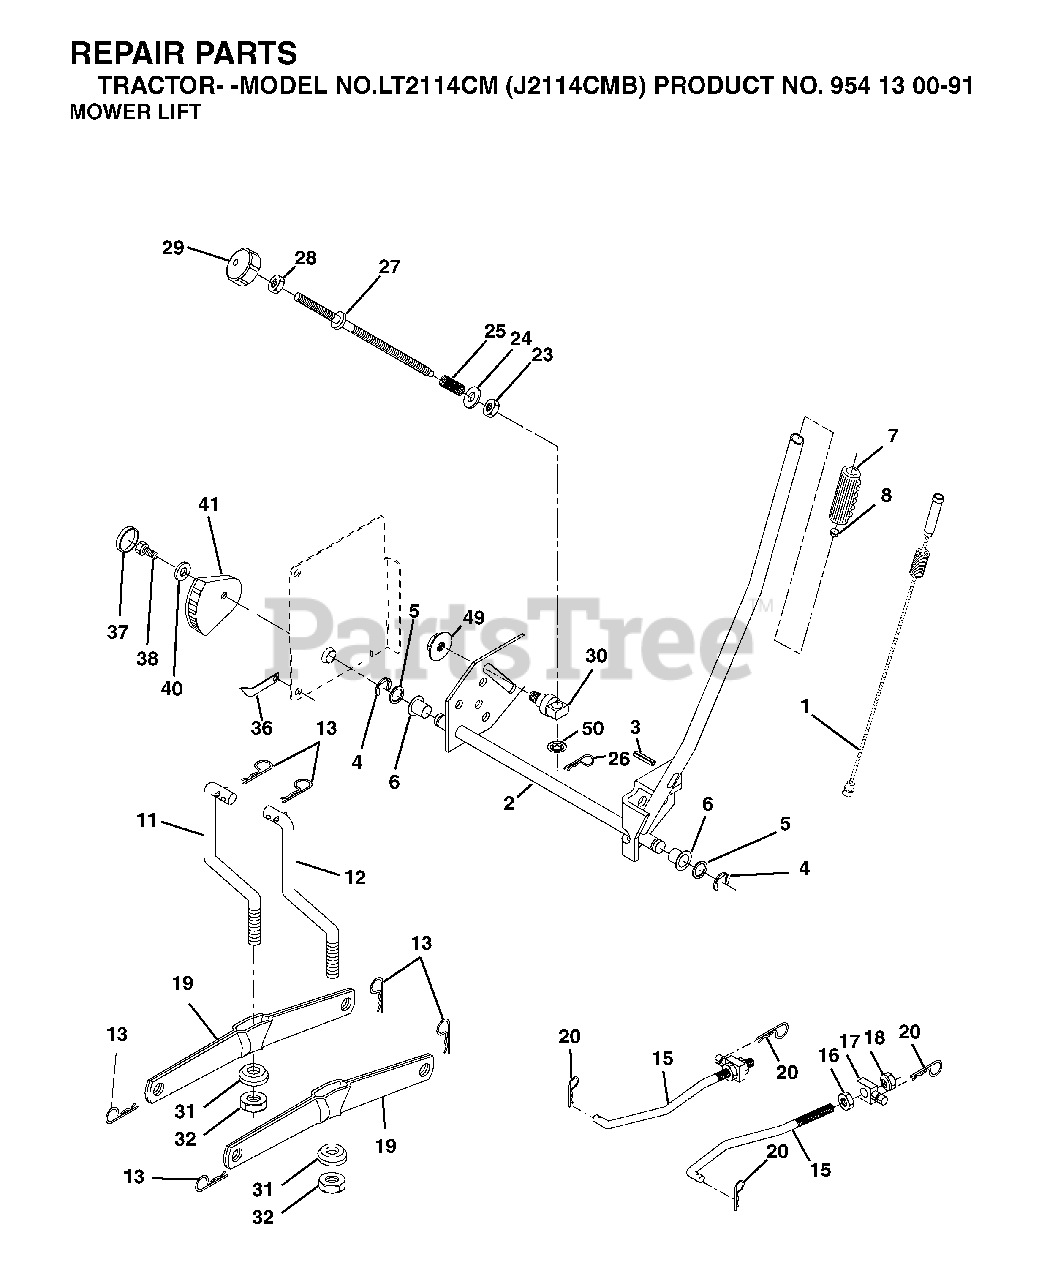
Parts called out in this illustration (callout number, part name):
1	WIRE ASM INNER W/ PLUNGER LT
2	SHAFT ASM R HANDLE
3	PIN GROOVE
4	RETAINING RING LT
6	BEARING.NYLON
7	GRIP HANDLE
8	PLUNGER BUT KIT
11	LINK
12	LINK
13	RETAINER-SPRNG RB
15	LINK.SUSPENSION.FRONT
16	NUT
18	NUT
19	ARM.REAR.SUSPENSION
20	SPRING RETAINER
25	SPRING**
26	RETAINER CLIP
27	ROD ADJ LIFT
28	NUT
29	KNOB INF 3/8-16
31	BEARING.PIVOT.LIFT
32	NUT CROWNLOCK 3/8-24
36	POINTER, HEIGHT INDICATOR
37	PLUG,HOLE
38	SCREW 5/16-18X1
41	HEIGHT INDICATOR
49	NUT
50	NUT PUSH M
